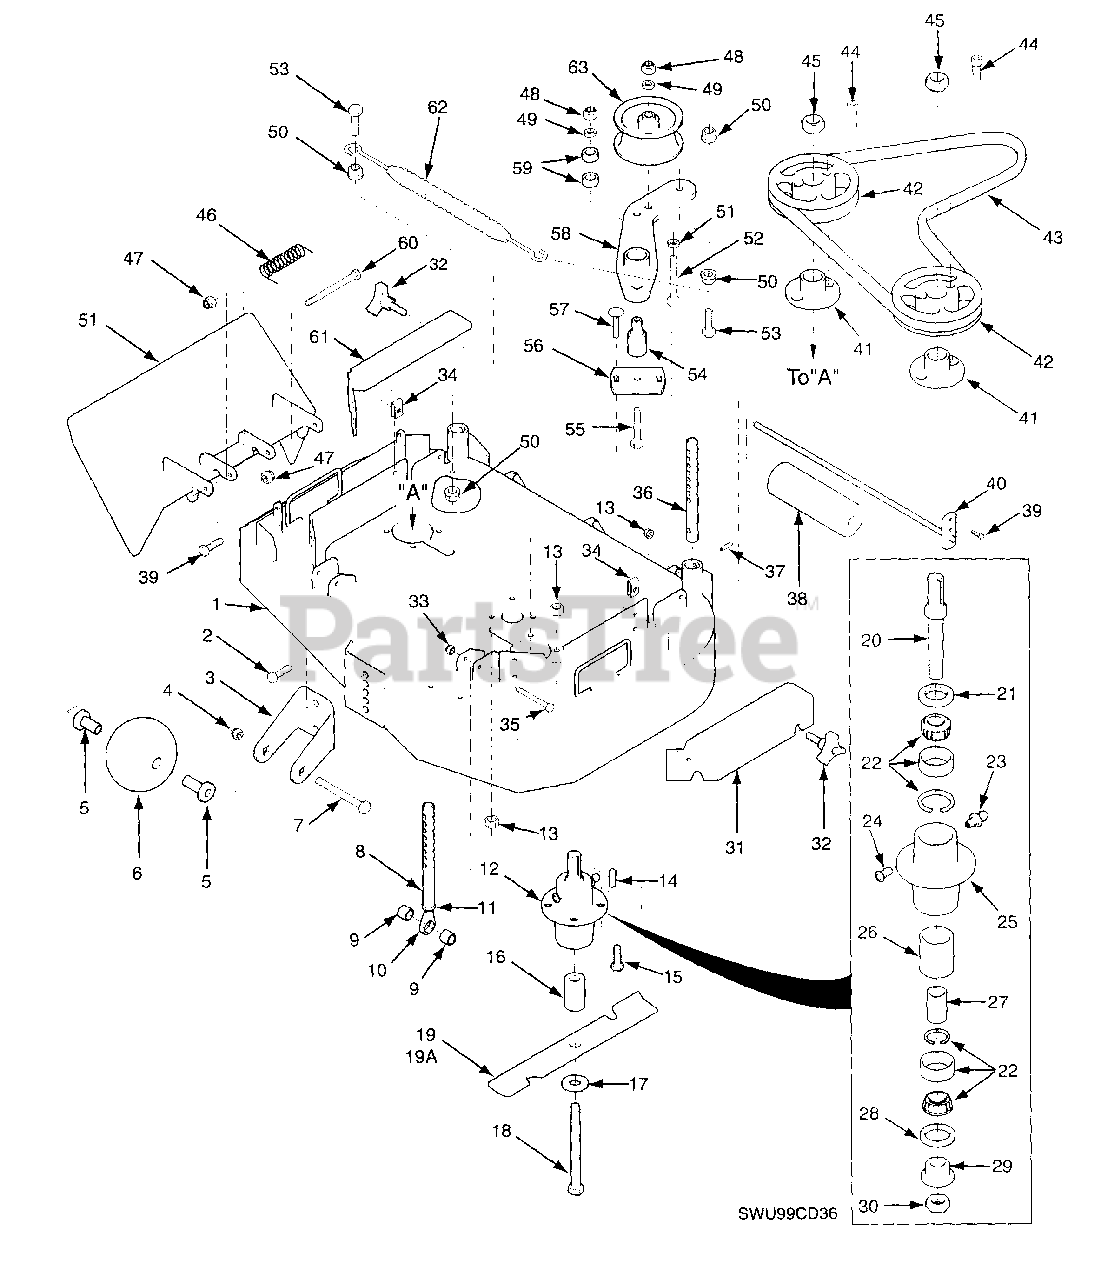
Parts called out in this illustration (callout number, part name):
1	Cutter Deck
2	Capscrew, 3/8-16 x 1.0" Serrated Flange Hex Hd
3	Bracket, Anti-Scalp Wheel
4	Lock Nut, 3/8-16 Center Lock
5	Bushing, 376 ID Oilite
6	Wheel, Anti-Scalp
7	Bolt, Carriage 3/8-16 x 4.0"
8	Pin Assy., Deck Adj.
9	Spacer, Deck Adjustment Pin
10	Rod End, Male 3/8-24 RH Thread
11	Nut, 3/8-24 Jam
12	Spindle Assembly
13	Nut, 5/16-18 Serrated Flange
14	Key, 1/4 x 1/4 x 2.0"
15	Bolt, Hex Head 5/16-18 x 1.25"
16	Spacer, Spindle
17	Flatwasher, 5/8 W
18	Bolt, hex Head 5/8-11 x 9.50"
19	Cutter Blade, 18"
19A	Cutter Blade, 18" Hi Lift
20	Spindle Shaft
21	Seal, Cutter Spindle Top
22	Tapered Bearing Set
23	Grease Fitting
24	Relief Fitting, Cutter Spindle
25	Spindle Housing
26	Spacer, Outside
27	Spacer, Inside
28	Seal, Cutter Spindle Bottom
29	Spindle Bushing
30	Nut, Spindle
31	Belt Cover, LH
32	Wing Nut, 3/8-16
33	Nut, 3/8-16 Elastic Stop
34	U-Nut, 3/8-16
35	Bolt, Hex Head 3/8-16 x 2.50"
36	Pin, Deck Adj. Rear
37	Pin, Sloted Spring 3/16 x 1.50"
38	Guide, Roller
39	Bolt, Hex Head 5/16-18 x 1.0"
40	Roller Shaft
41	Tapered Hub
42	Pulley
43	Belt, Cutter Deck
44	Capscrew, Socket Head. 1/4-20 x 1.375"
45	Hex Nut, 5/8-11
46	Spring, Chute Return
47	Hex Nut, 5/16-1B Elastic Stop
48	Hex Nut, 3/8-16 Elastic Stop
49	Flatwasher, 3/8 (.938 x .391 x .105)
50	Nut, 3/8-16 Serrated Flange
51	Discharge Chute
52	Capscrew, Hex Head 3/8-16 x 3.75"
53	Capscrew, Hex Head 3/8-16 x 1.50"
54	Pivot, Idler - Long
55	Capscrew, Hex Head 38/16 x 3.25"
56	Base, Idler Pivot
57	Bolt, Carriage 5/16-18 x 1.0"
58	Idler Arm Weldment
59	Ball Bearing
60	Bolt, Hex Head 5/16-18 x 4.25"
61	Belt Cover, RH
62	Spring, Deck Idler
63	Pulley, Idler
